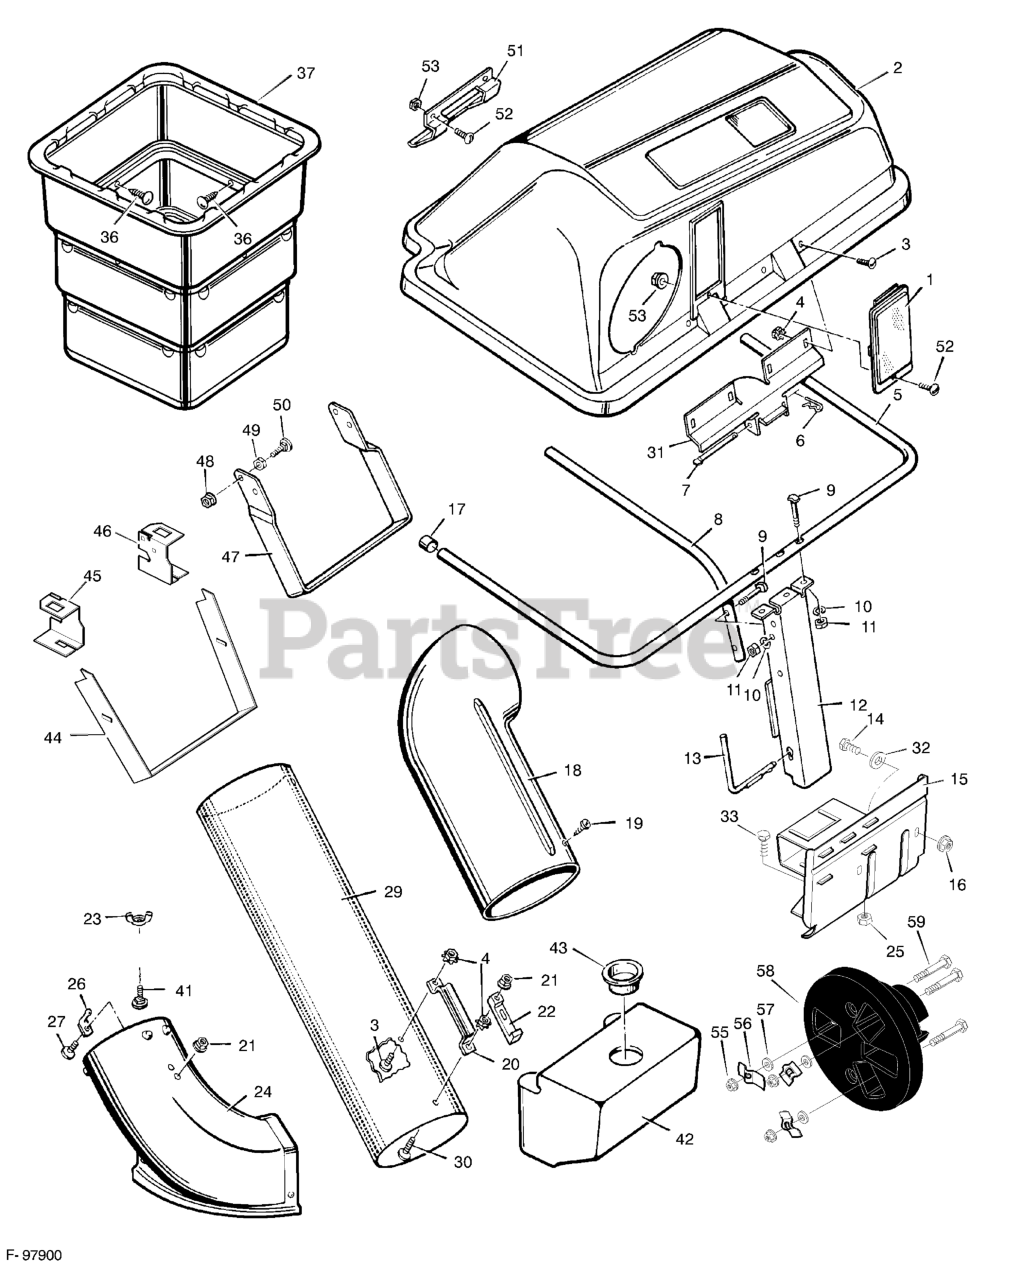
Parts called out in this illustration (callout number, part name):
4	Locknut
6	Pin, Hair
7	Pin, Hinge
8	Tube, Center
9	Bolt, Special
10	Lockwasher
11	Nut, Hex
12	Channel Assembly
13	Pin, Channel
14	CAPSCREW, Hex Head, 5/16-18 x 1
15	Mount Assembly, Bagger
16	Nut, Hex
17	Cap, End
20	HANDLE, Connect Tube
21	Locknut, Flange
22	Latch, Rubber
23	Wingnut
24	Tube, Extension
25	Hex Nut
26	Pin, Latch
27	Bolt, Carriage
29	Tube, Connector
31	Hinge, Cover
33	Bolt, Hex
36	Fastener, Plastic
37	Containers (Quantity 2)
41	Bolt, Carriage
42	Shell, Front Weight
43	Plug, Front Weight
44	Support, Weight (Type A)
45	Bracket, Right Hanger
46	Bracket, Left Hanger
47	Support Weight (Type B)
48	Nut, Flange
49	Nut, Jam
50	Carriage, Bolt
51	Handle, Plastic
53	Nut, Hex
55	Nut, Flange
56	Clip, Wheel
57	Retainer
58	Weight, Wheel
